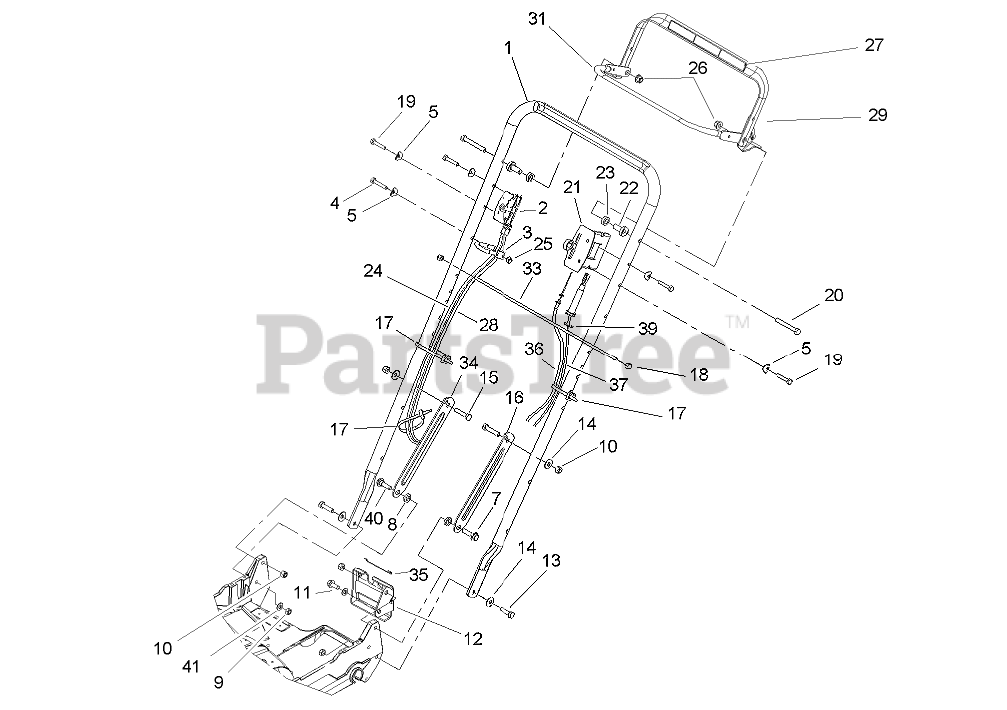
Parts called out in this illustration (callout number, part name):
1	HANDLE-PROLINE
2	CONTROL-SHIFT
3	GUIDE-ROPE
4	SCREW-HH
5	WASHER
7	SCREW-SHOULDER
8	SPACER
9	NUT-LOCK, NI
10	NUT-LOCK, NI
11	SCREW-HWHTF
12	BRACKET-ADJUSTMENT, TRACTION
13	SCREW-HH
14	WASHER-BELLEVILLE
15	SCREW-HH
16	LATCH-HANDLE, LH
17	TIE-CABLE
18	NUT-CAP
19	SCREW-HH
20	SCREW-HH
21	CONTROL-THROTTLE
22	SPACER-SUPPORT
23	SPACER-NYLON
24	CABLE-BRAKE
25	NUT-LOCK, NI
26	NUT-LOCK, NI
27	DECAL-OPERATION
28	CABLE-SHIFT
29	TRACTION BAIL ASM
31	BRAKE BAIL ASM
33	ROD-SUPPORT, BAG
34	LATCH-HANDLE, RH
35	RETAINER-CABLE
36	CABLE-TRACTION
37	THROTTLE CABLE ASM
39	E-RING
40	SCREW-SHOULDER
41	WASHER-PLAIN
